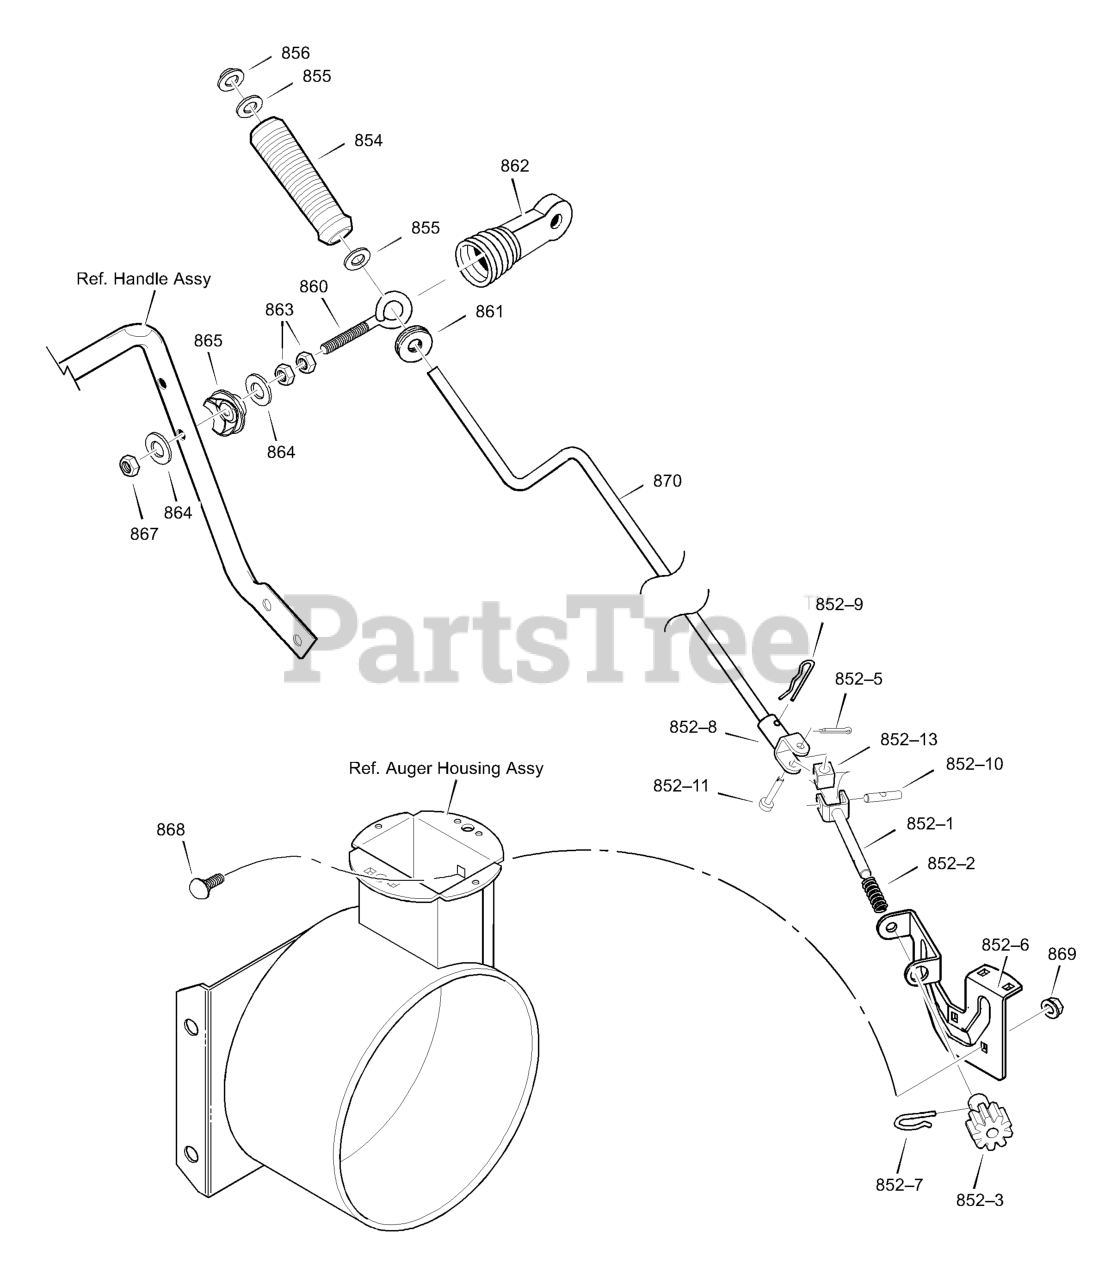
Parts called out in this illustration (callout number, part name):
852-1	ASSEMBLY, YOKE & ROD
852-2	SPRING, COMPRESSION
852-3	GEAR, CHUTE ROTATION 9T
852-5	PIN, COTTER
852-6	BRACKET, GEAR MOUNT
852-7	PIN, HAIR
852-8	ASSEMBLY, YOKE ADAPTER YZ
852-9	PIN, HAIR
852-10	PIN, UNIVERSAL JOINT
852-11	PIN, CLEVIS
852-13	HOUSING, UNIVERSAL
854	KNOB, SLEEVE
855	FLATWASHER
856	NUT, PUSH ON 3/8"
860	EYE BOLT 3/8-16X6.50
861	GROMMET, EYE BOLT
862	BOOT, EYE BOLT
863	NUT, 3/8-16 HEXJAM
864	FLATWASHER .406X.81X.066
865	ADAPTER, BOOT (2 REQUIRED)
867	NUT, 3/8-16 HEXNYL
868	BOLT, CARRIAGE 1/4-20 X 1.00
869	NUT
870	CRANK, ASSY CHUTE
